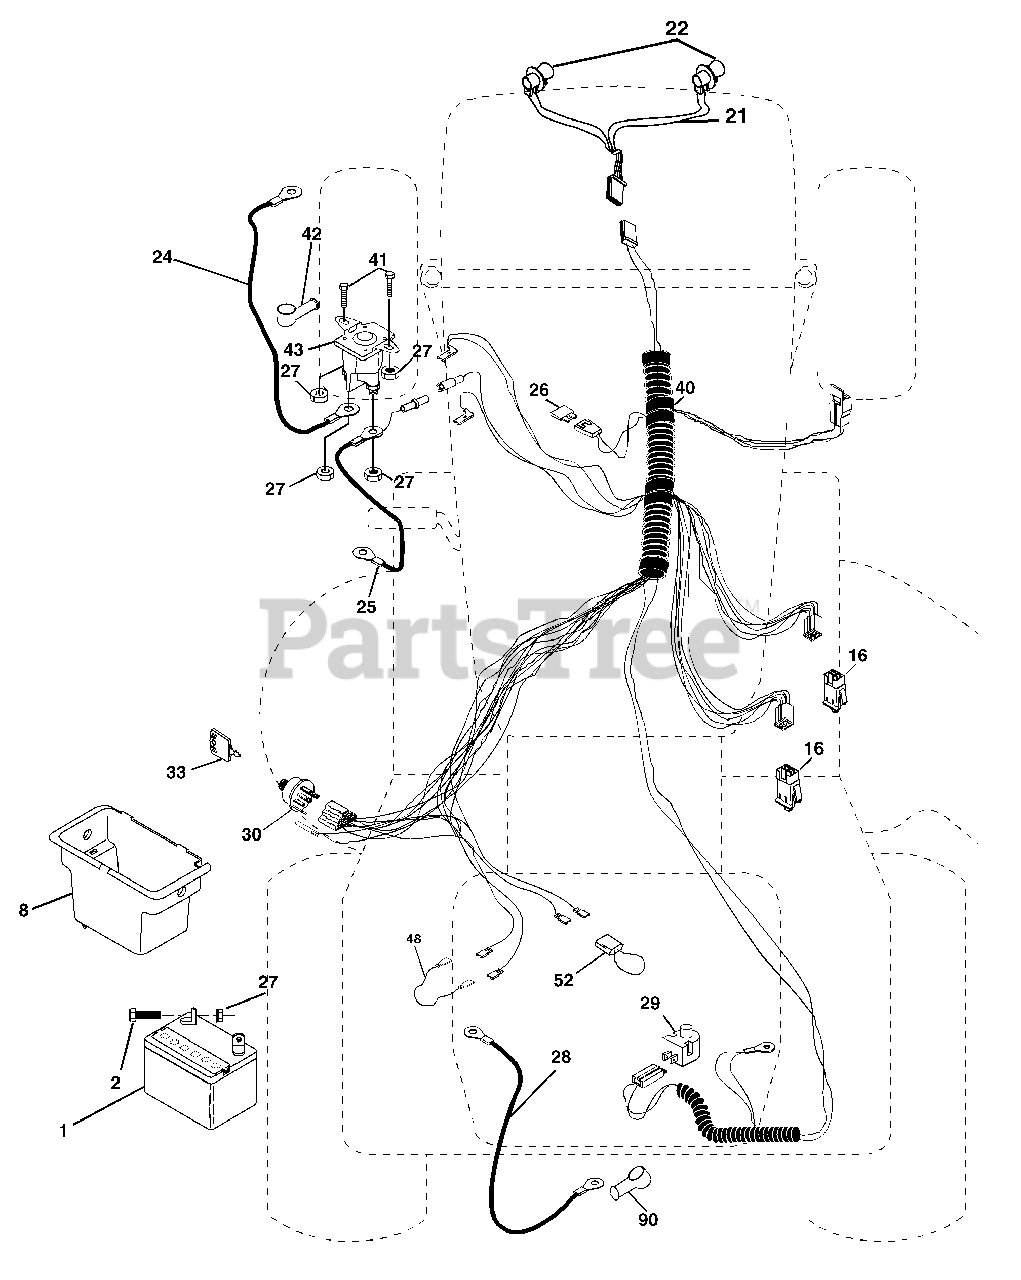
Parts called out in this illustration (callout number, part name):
1	Battery 12 Volt 25 Amp
2	Bolt Hex Hd 1/4-20unc x 3/4
8	Box Battery
16	Switch Interlock Push -In
21	Harness Asm Light W/4152J
22	Bulb Light #1156
24	Cable Battery 6 Ga 11" red
25	Cable Battery 6 Ga w/16 wire, red
26	Fuse 20 AMP
27	Nut Keps Hex 1/4-20 Unc
28	Cable Ground 6 Ga 12" black
29	Switch Plunger Nc Gray
30	Switch Ign
33	Key Ign
40	Harness Ign
41	Bolt Blk Fin Hex 1/4-20 x 1/2
42	Cover Terminal Red
43	Solenoid
48	Adapter Ammeter
52	Protection Wire Loop
90	Cover Terminal
